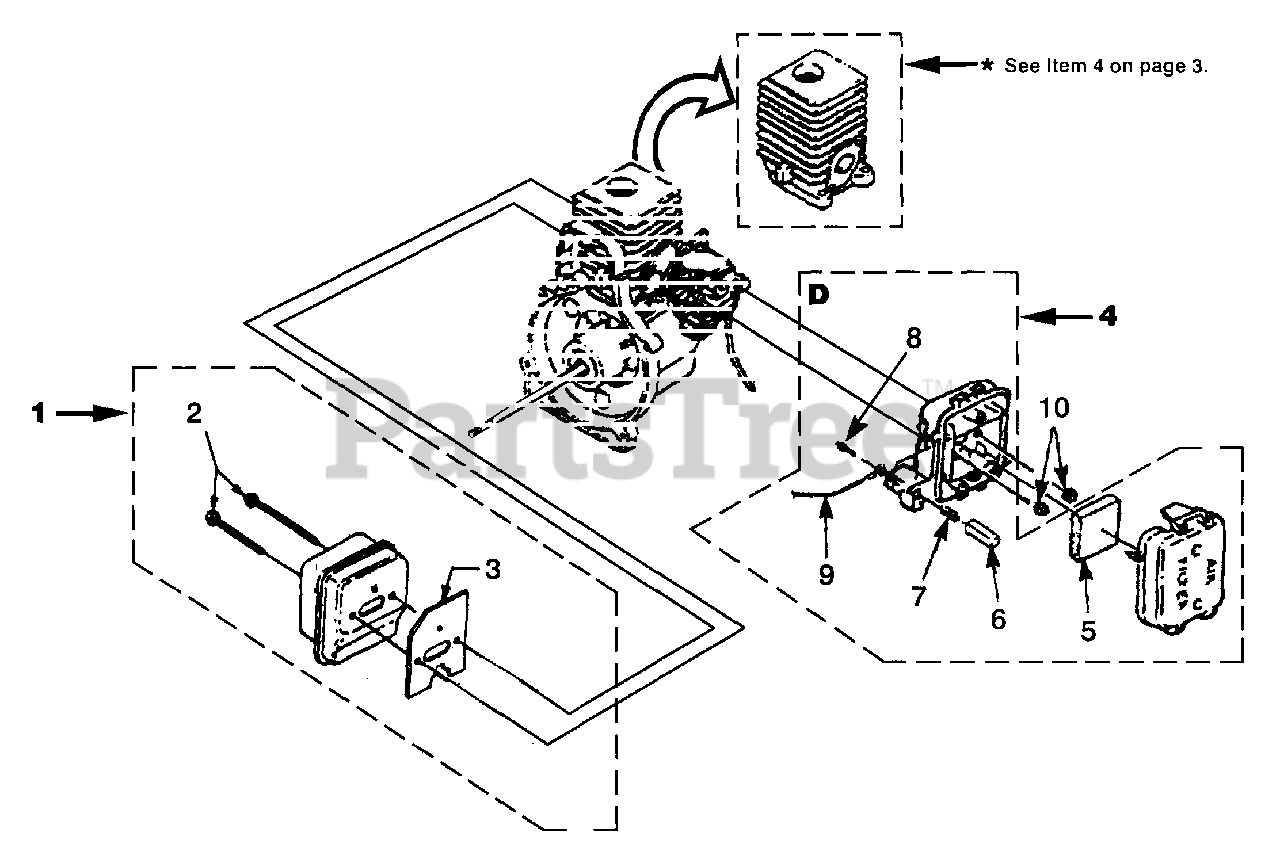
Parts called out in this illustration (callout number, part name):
1	MUFFLER COMPLETE
2	SCREW - Sems Hex (10-24 X 2-1/2")
3	GASKET - Muffler
4	AIR FILTER KIT
5	FILTER - AIR
6	BUTTON - Switch
7	SPRING - Compression
8	SCREW - Plastite (#6)
9	LEAD - Electrical
10	NUT - Hex (10-24)
